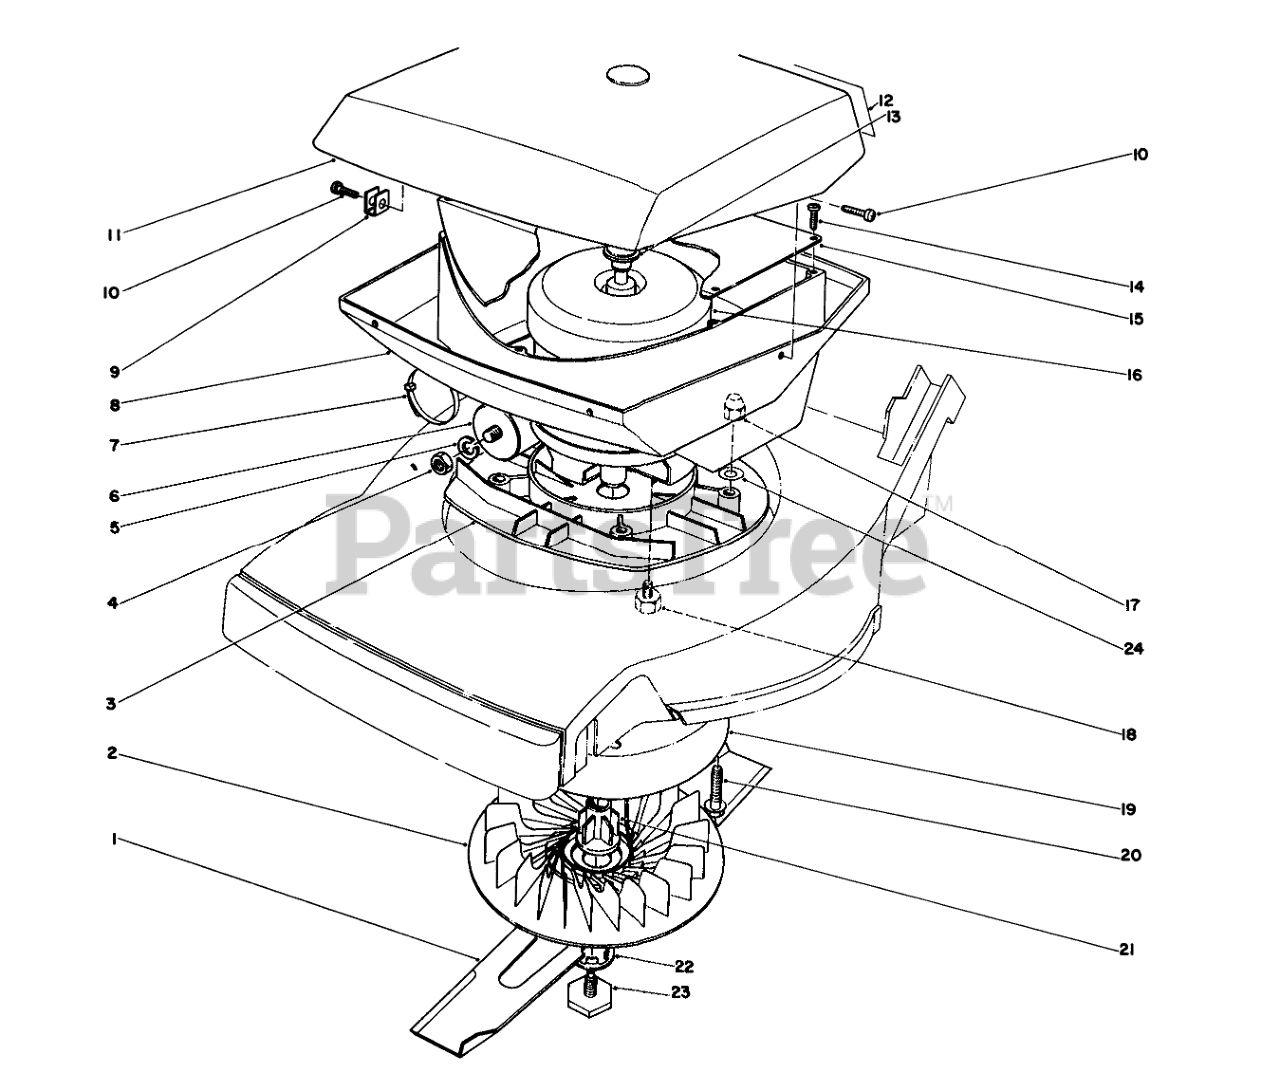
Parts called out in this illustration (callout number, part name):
1	42 CM BLADE
3	Plate-Motor Mount
5	10-24 X 1/2 FIL HD MS
6	Capacitor
7	TIE-CABLE
8	Shroud-Lower Electric
9	Clip-"U" Type
10	SCREW-PPH
11	Shroud Assembly-Upper Electric
12	Decal-Warning
13	Rotation Indicator
14	SCREW-PPH
15	Plate-Air Baffle
16	Motor (Incl. Ref. #4-7)
17	INSULATED NUT
18	Screw-Insulated
19	Fan Shroud
20	Capscrew-Hex Washer Head
21	Hub-Blade
22	Retainer-Plate
23	Screw-Blade
